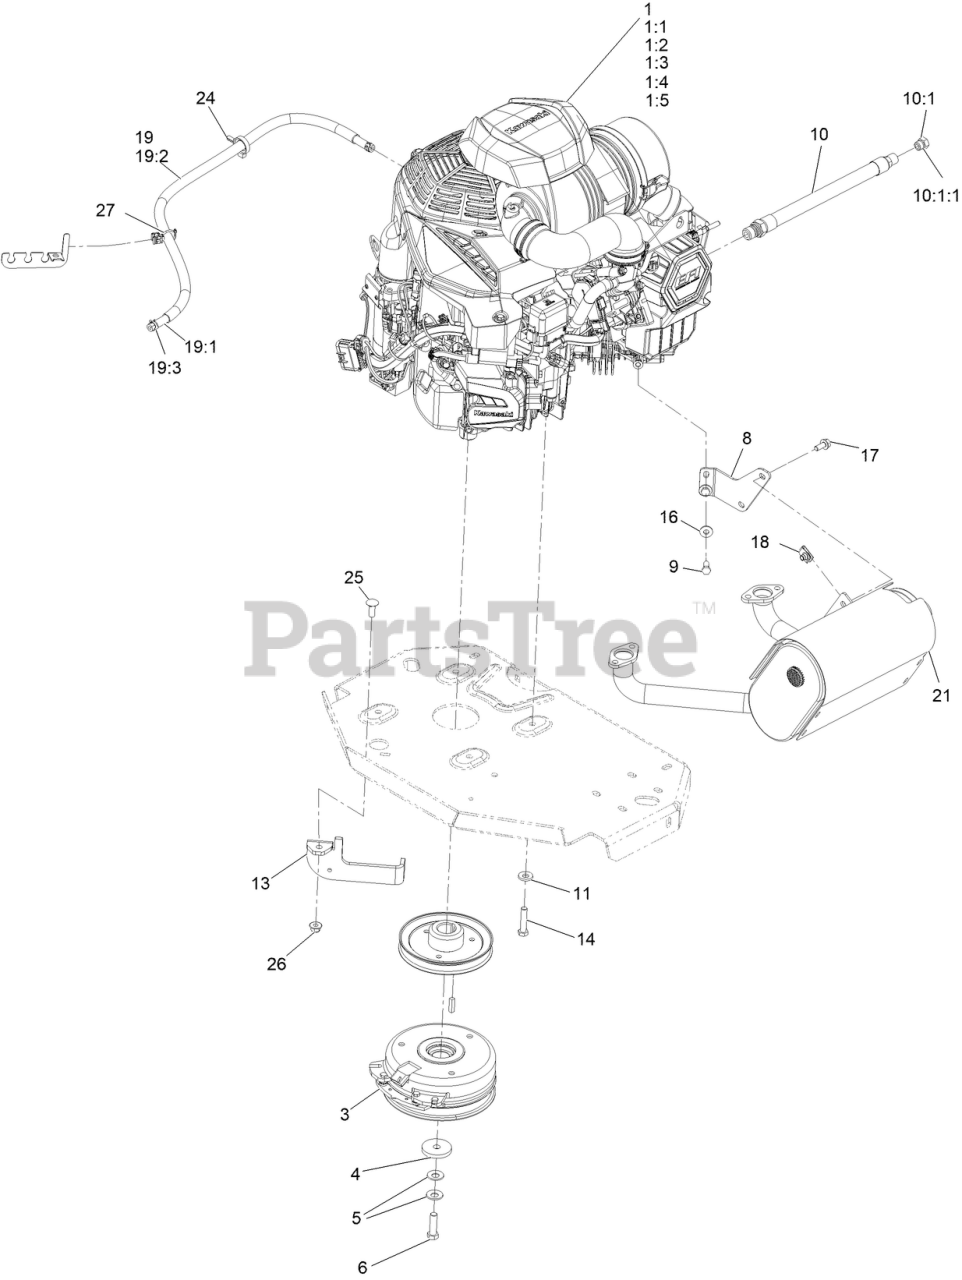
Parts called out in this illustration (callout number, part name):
1:1	FILTER-OIL KAW
1:2	ELEMENT-FILTER, AIR (OUTE
1:3	ELEMENT-FILTER, AIR (INNE
1:4	FILTER-FUEL
1:5	SPARK PLUG
3	CLUTCH KIT
4	WASHER-CLUTCH
5	WASHER-SPRING
6	SCREW-HH 7/16-20 X 1 1/2 W/LOCTITE
8	BRACKET-MUFFLER 820KAW
9	SCREW-HH
10	ENGINE OIL DRAIN HOSE ASM
10:1	PLUG-HH
10:1:1	O-RING
11	WASHER-BELLEVILLE
13	Bracket-Clutch Anchor
14	SCREW-HH
16	WASHER-SPRING
17	SCREW-HHF
19	FUEL LINE ASM
19:1	HOSE-FUEL
19:2	SLEEVE-THERMAL
19:3	CLAMP-HOSE
21	MUFFLER-KAWASAKI FX820V
24	CLAMP-HOSE
25	SCREW-CARR
26	NUT-HF, NI
27	Clip-Edge
